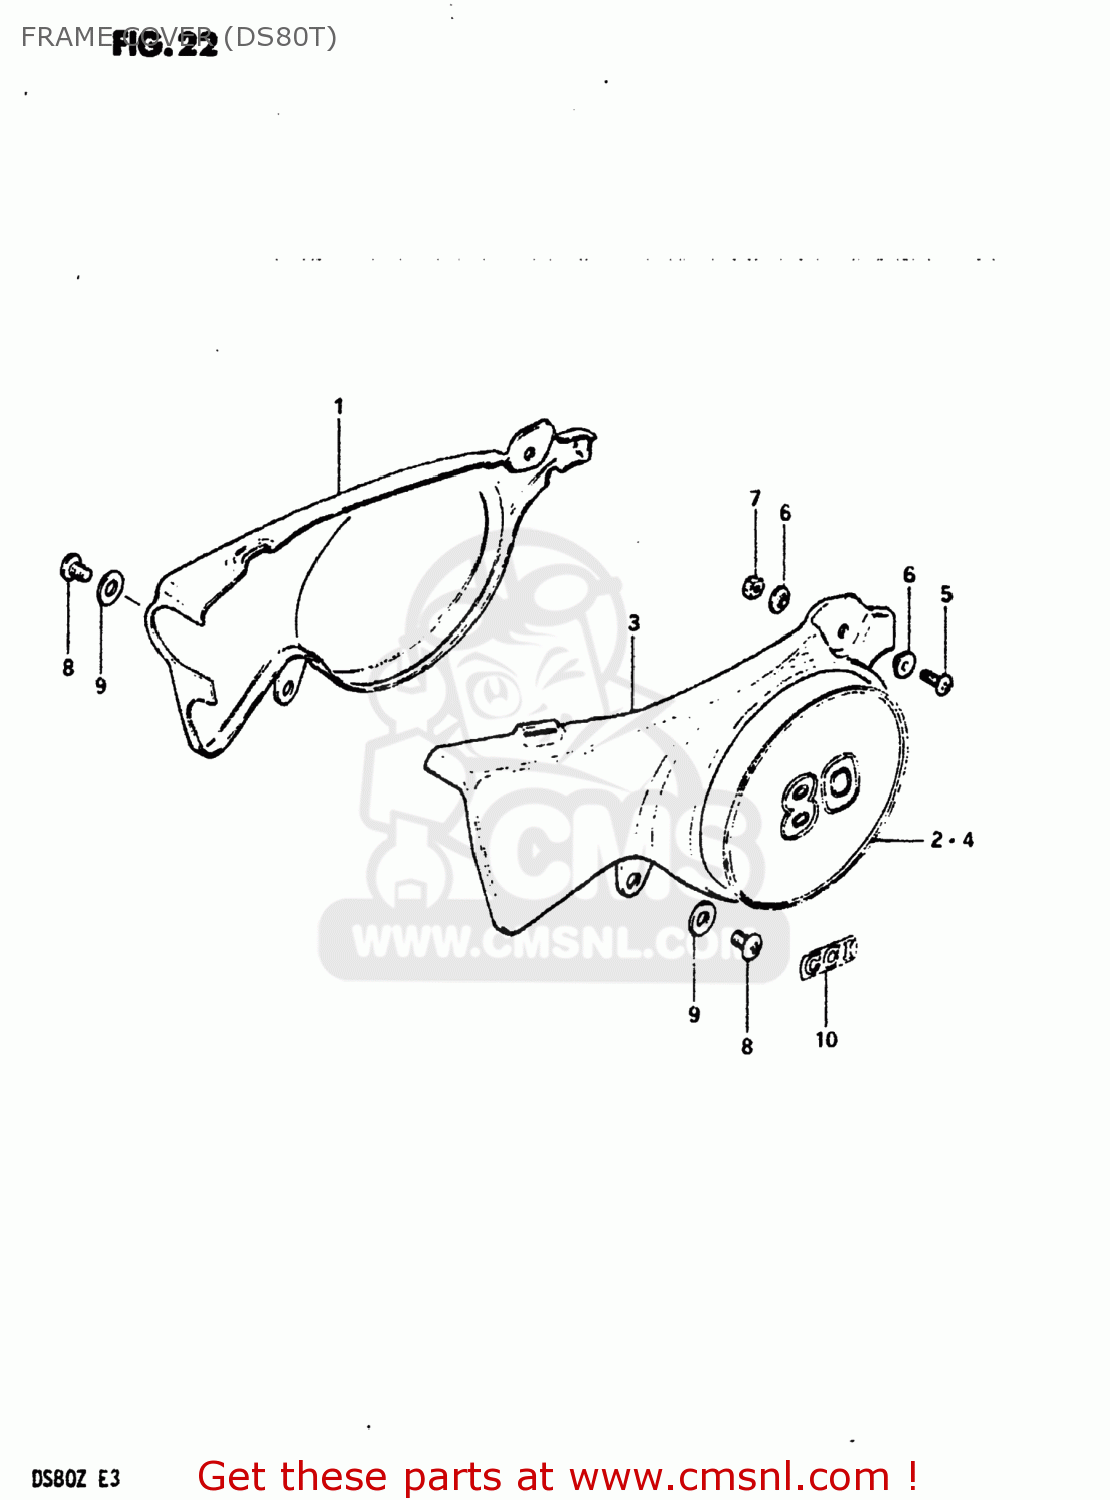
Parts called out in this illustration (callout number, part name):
1	COVER,FRAME,RIGHT
2	EMBLEM
3	COVER,FRAME,LEFT
4	EMBLEM,FRAME COVER
5	SCREW
6	WASHER
7	NUT
8	SCREW 6X12
9	WASHER
10	EMBLEM,CCIS
